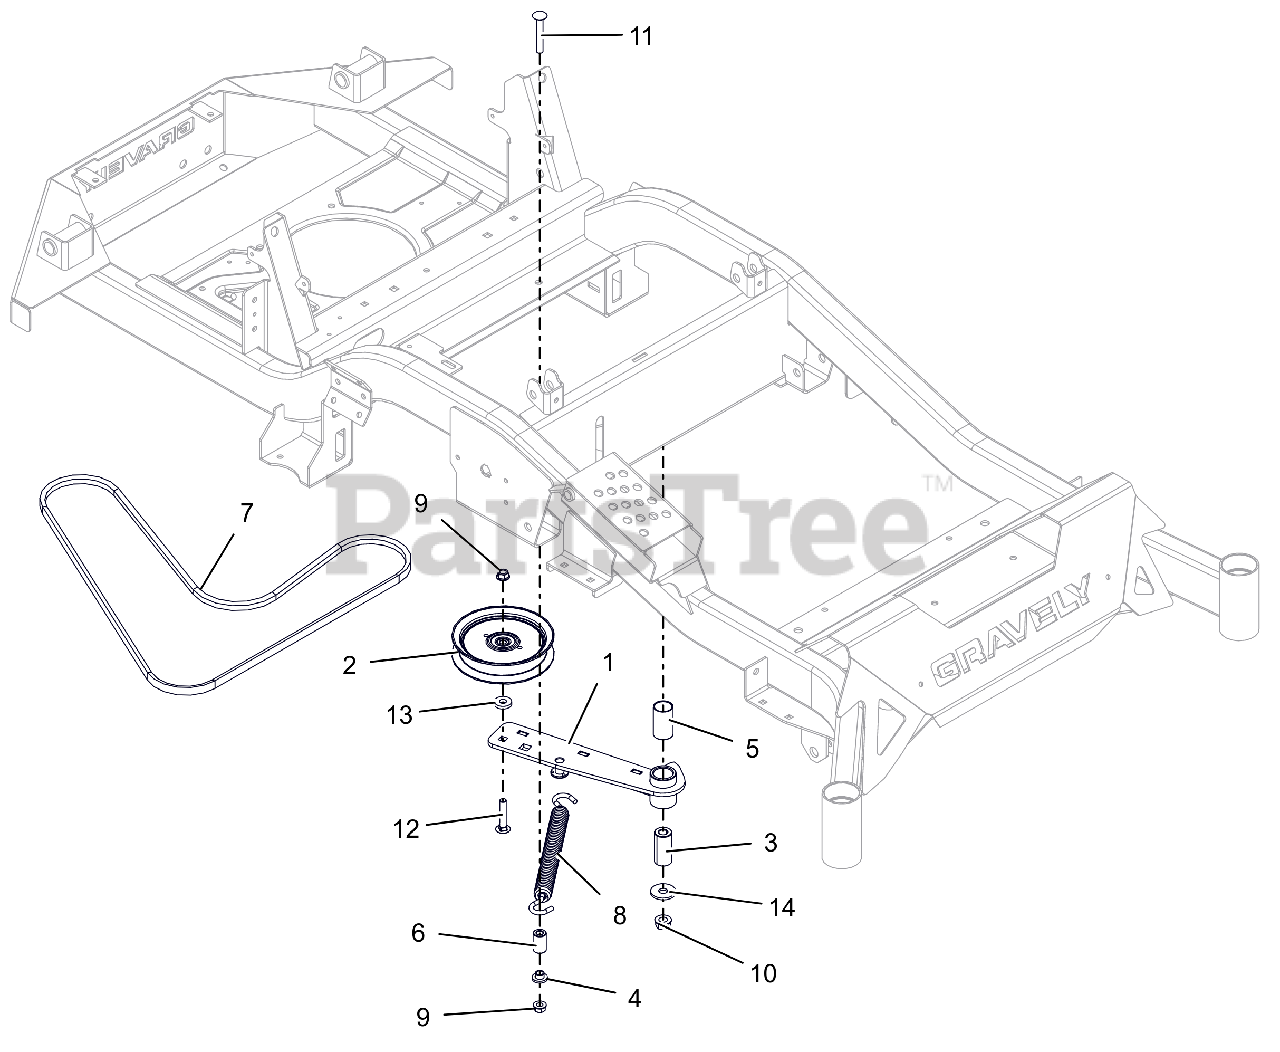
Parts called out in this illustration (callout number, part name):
1	WLDMT, HYDRO DRIVE IDLER ARM
2	IDLER, FLAT 5.00"
3	BSHG, SPCR .502X.997X2.03 PM
4	BSHG-FLG .385X.500X.875X.406
5	BSHG, 1.00X1.125X1.937
6	BUSHING, SLV .380X.750X1.190
7	V-BELT, 4L-WRAPPED
8	SPRING, EXTENSION
9	NUT-LK-TOP-FLG .38-16 ZC120
10	NUT-LK-TOP-FLG .500-13 GF ZCC
11	BLT, RHSSN.38-16X2.50 G5 ZCC
12	BLT, RHSN .38-16X2.00 G5 ZCC
13	WSHR, FLT .406X1.00X.188 ZCC
14	WSHR-FL-STL.511X1.44X.125ZC120
